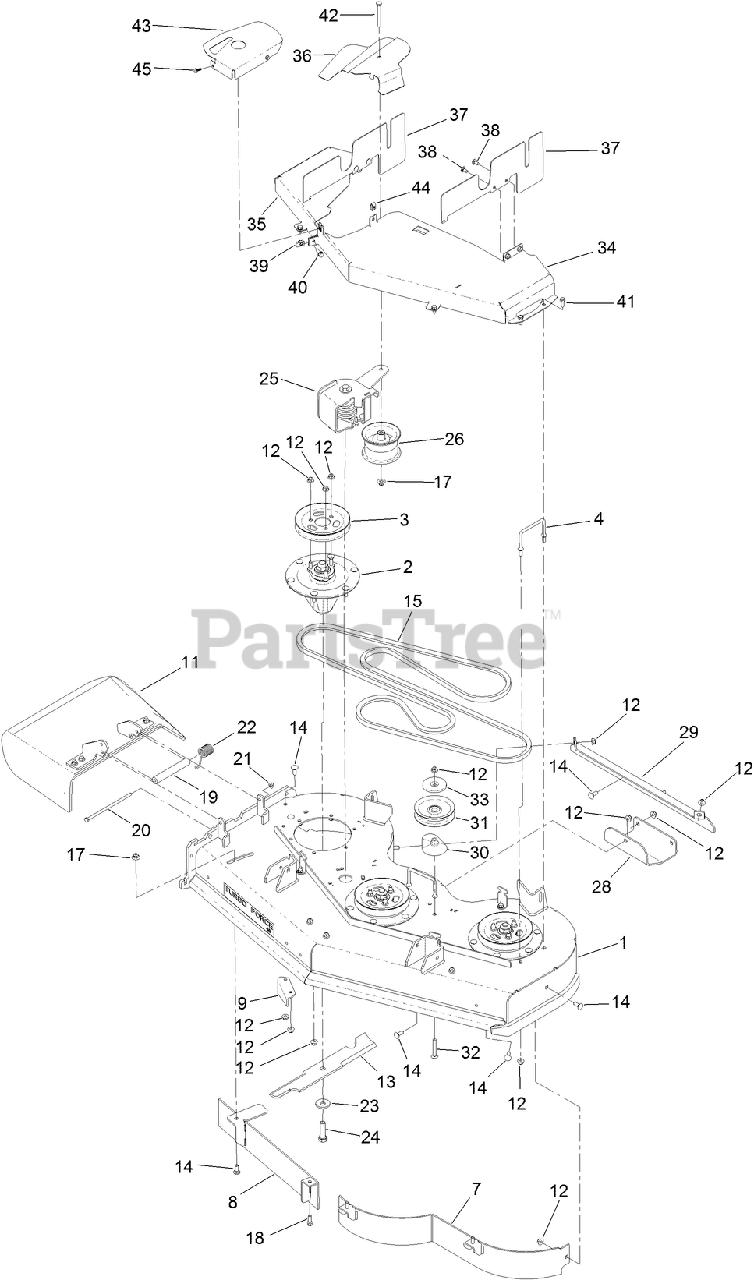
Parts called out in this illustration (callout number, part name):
1	DECK ASM
2	SPINDLE ASM
3	PULLEY
4	WIREFORM-COVER
7	48 INCH BAFFLE ASM
9	BAFFLE-DISCHARGE
11	DEFLECTOR ASM
12	NUT-HF, NI
13	BLADE-16.5 INCH (HIGH FLOW)
14	SCREW-HH
15	BELT-V
17	NUT-FLANGE, NI
19	SPACER
20	SCREW-HH
21	NUT-HF, NI
22	SPRING-TORSION
23	WASHER-BLADE BOLT, HEAVY
24	SCREW-BLADE
25	IDLER TORSION ASM
26	PULLEY-IDLER
29	BRACKET-SKID
30	SPACER-PULLEY
31	PULLEY-IDLER, FLAT
32	SCREW-CARR
33	SHIELD-DUST
34	COVER-BELT, LH, CE
35	COVER-BELT, RH CE
36	COVER-IDLER, CE
37	COVER-SIDE, LH (CE)
38	SCREW-CARR
39	NUT-U
40	SCREW-HHF
41	SCREW-HH
42	SCREW-HH
43	COVER-IDLER, CE
45	SCREW-HHF
